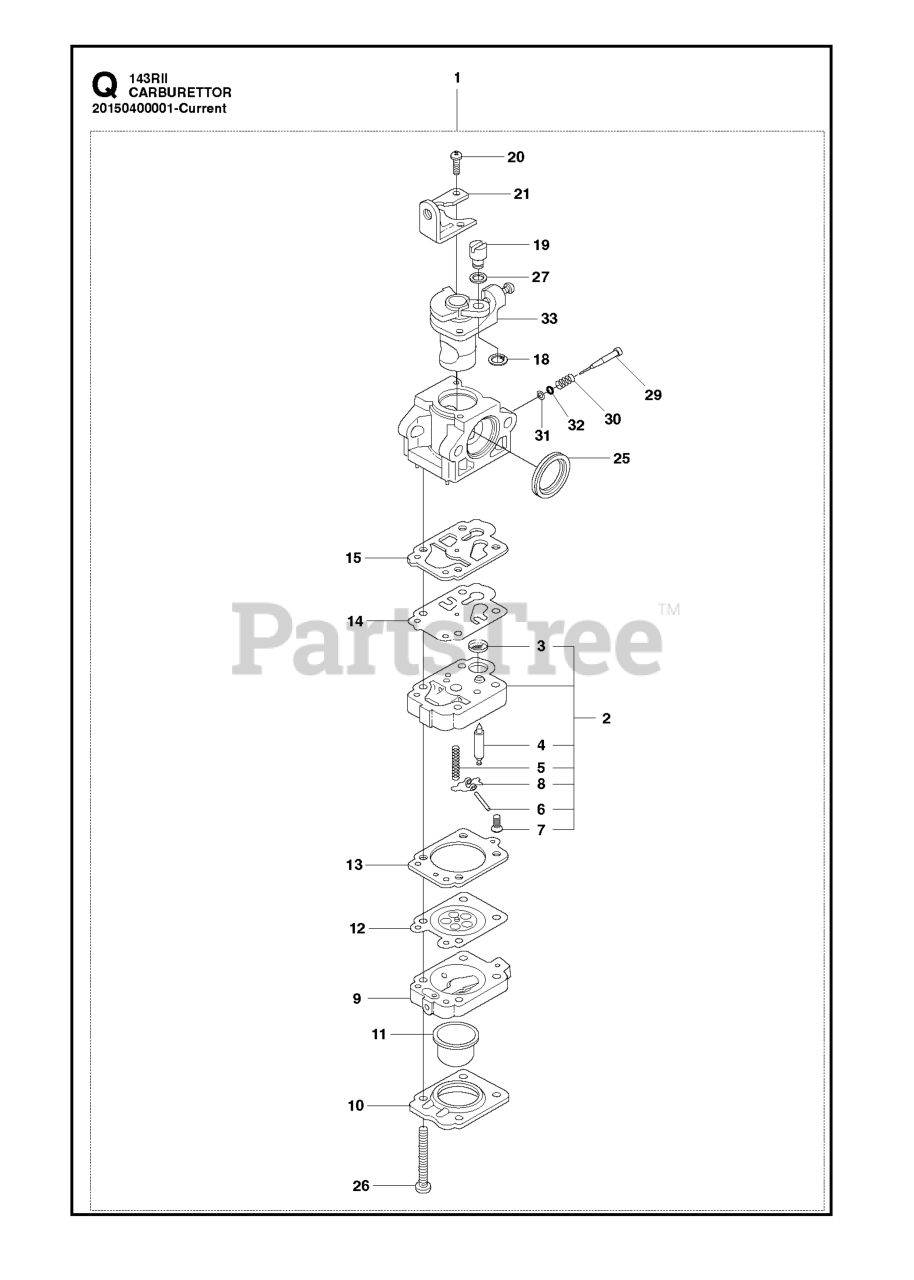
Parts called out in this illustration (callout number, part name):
3	SCREEN
4	VALVE INLET
25	RING PACKING
30	SPRING
